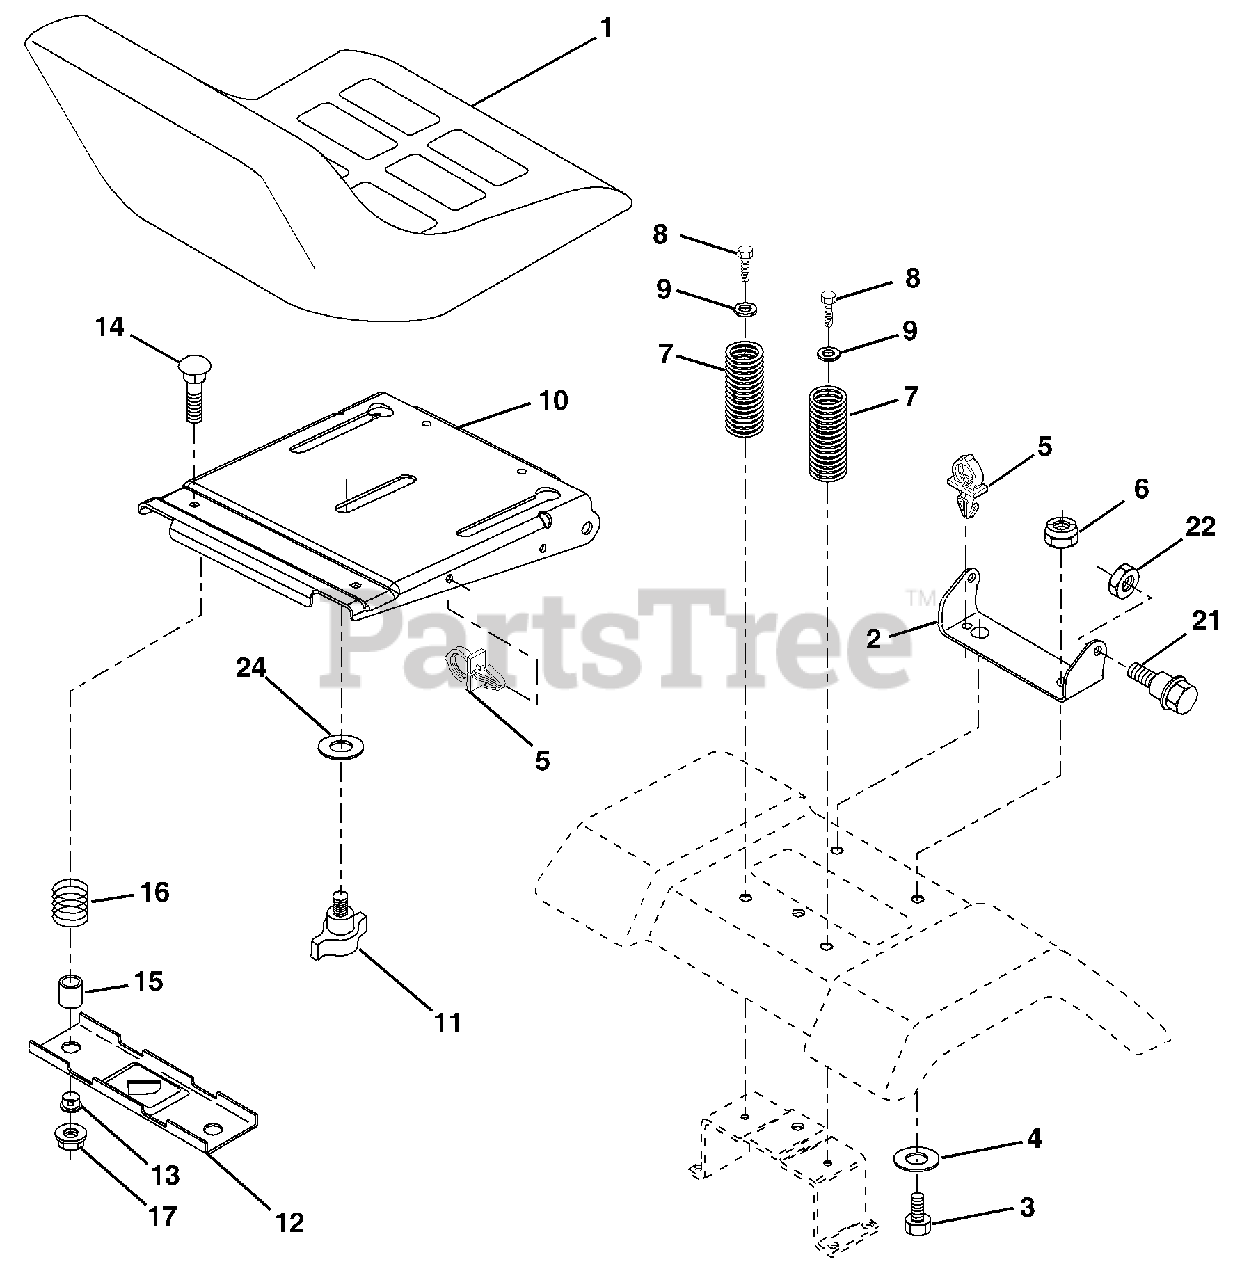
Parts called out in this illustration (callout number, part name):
2	Bracket Pivot
3	Bolt Fin Hex 3/8-16 unc x 1
4	Washer 13/32 x 1 x 10 Ga.
5	Clip Push-In
6	Nut Hex w/Ins. 3/8-16 unc
7	Spring Seat Cprsn 2 250 Blk Zi
8	Screw 3/8-16 x 1.5
9	Washer 13/32 x 1 x 14 Ga.
10	Pan Seat
11	Knob Seat
12	Bracket Mounting Switch
13	Bushing Snap Blk Nyl 50 Id
14	Bolt Rdhd Sqnk 1/4-20 x 1-1/2
15	Spacer Split 28x 88
16	Spring Cprsn
17	Nut Lock 1/4 Lge Flg Gr. 5 Zinc
21	Bolt Shoulder 5/16-18 Unc
22	Nut Hex Lock W/Ins 5/16-18
24	Washer 17/32 x 1-3/16 x 12 Ga.
